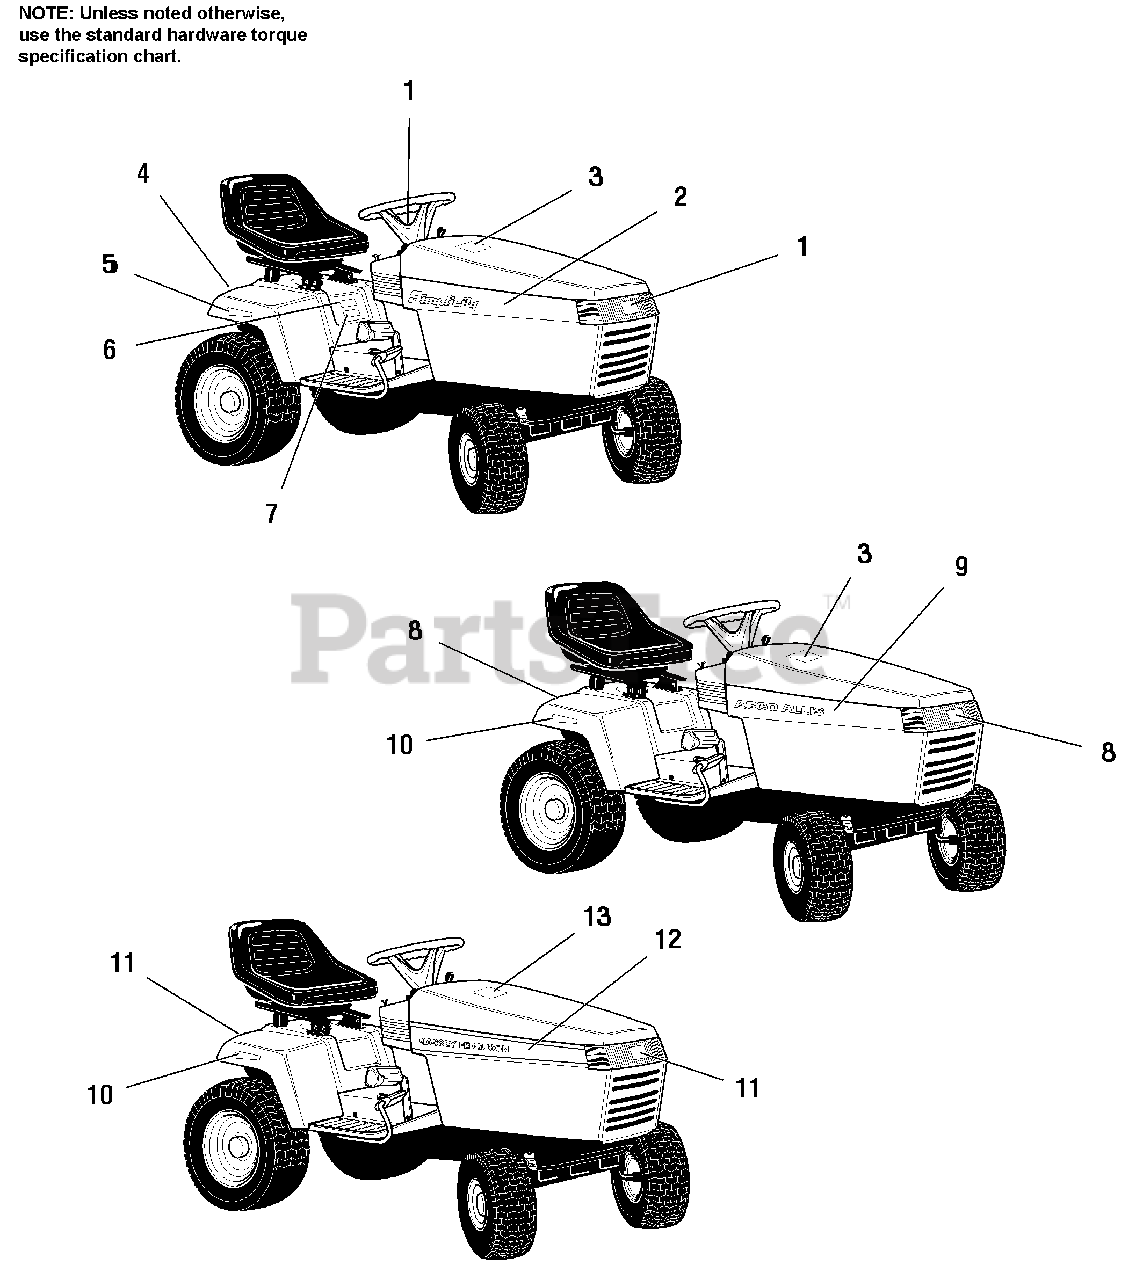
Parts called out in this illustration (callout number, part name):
1	DECAL, Simplicity Icon
2	DECAL, RH Hood, Simplicity
2	DECAL, LH Hood, Simplicity
3	DECAL, Paint, Simplicity & AGCO-Allis
4	DECAL, Simplicity Logo with Icon
5	DECAL, Controlled Traction, Simplicity
6	DECAL, Seat Deck, Broadmoor, Simplicity
7	DECAL, Model, Simplicity Broadmoor - Hydro 16 HP
7	DECAL, Model, Simplicity Broadmoor - Hydro 14V-Twin
7	DECAL, Model, Simplicity Broadmoor - Hydro 16V-Twin
7	DECAL, Model, Simplicity Broadmoor - Hydro 18V-Twin
8	DECAL, AGCO-Allis Icon
9	DECAL, LH Hood - AGCO-Allis 1616VH
9	DECAL, RH Hood - AGCO-Allis 1616VH
9	DECAL, RH Hood - AGCO-Allis 1614VH
9	DECAL, LH Hood - AGCO-Allis 1614VH
9	DECAL, RH Hood - AGCO-Allis 1615H
9	DECAL, LH Hood - AGCO-Allis 1615H
9	DECAL, LH Hood - AGCO-Allis 1618VH
9	DECAL, RH Hood - AGCO-Allis 1618VH
10	DECAL, Controlled Traction, AGCO-Allis & Massey Ferguson
11	DECAL, Massey Ferguson Icon
12	DECAL, LH Hood, Massey Ferguson 2616H
12	DECAL, RH Hood, Massey Ferguson 2616H
12	DECAL, RH Hood, Massey Ferguson 2615H
12	DECAL, LH Hood, Massey Ferguson 2615H
12	DECAL, LH Hood, Massey Ferguson 2618H
12	DECAL, RH Hood, Massey Ferguson 2618H
13	DECAL, Paint, Massey Ferguson
